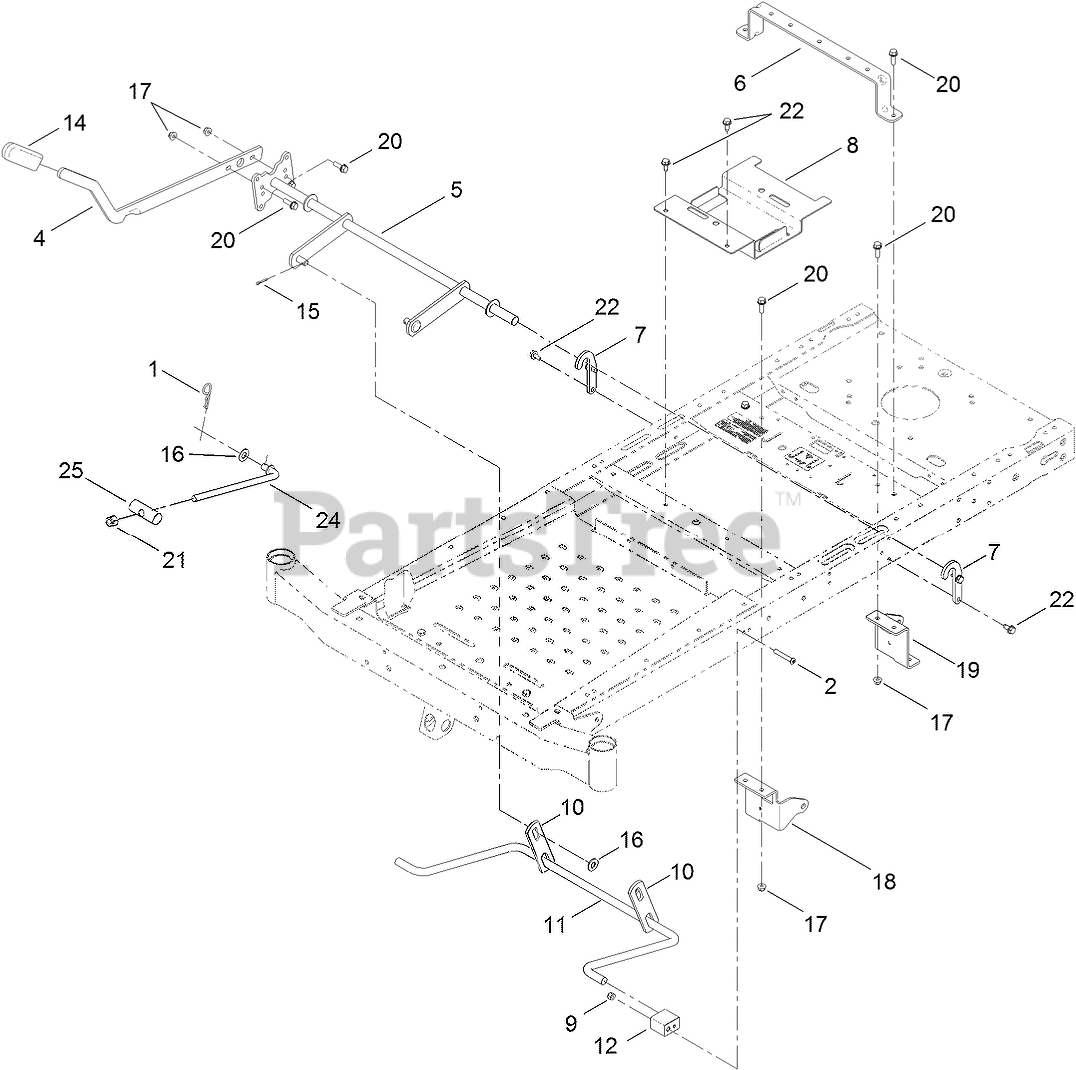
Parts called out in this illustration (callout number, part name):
1	PIN-COTTER
2	SCREW-HSBH
4	LEVER-LIFT
5	LIFT-DECK, WIDE
6	BRACE-SEAT, REAR
7	BRACKET-LIFT
8	BRACKET-BATTERY
9	NUT-LOCK, NI
10	LINK-LIFT
11	ARM-LIFT, REAR (WIDE)
12	BLOCK-PIVOT
14	GRIP-LEVER
15	PIN-COTTER
16	WASHER-FLAT
17	NUT-HF, NI
18	MOUNT-HYDRO, FRONT (RH)
19	MOUNT-HYDRO, FRONT (LH)
20	SCREW-HHF
21	NUT-HEX
22	SCREW-HWHTF
24	ROD-TRUNION
25	PIN-PIVOT
